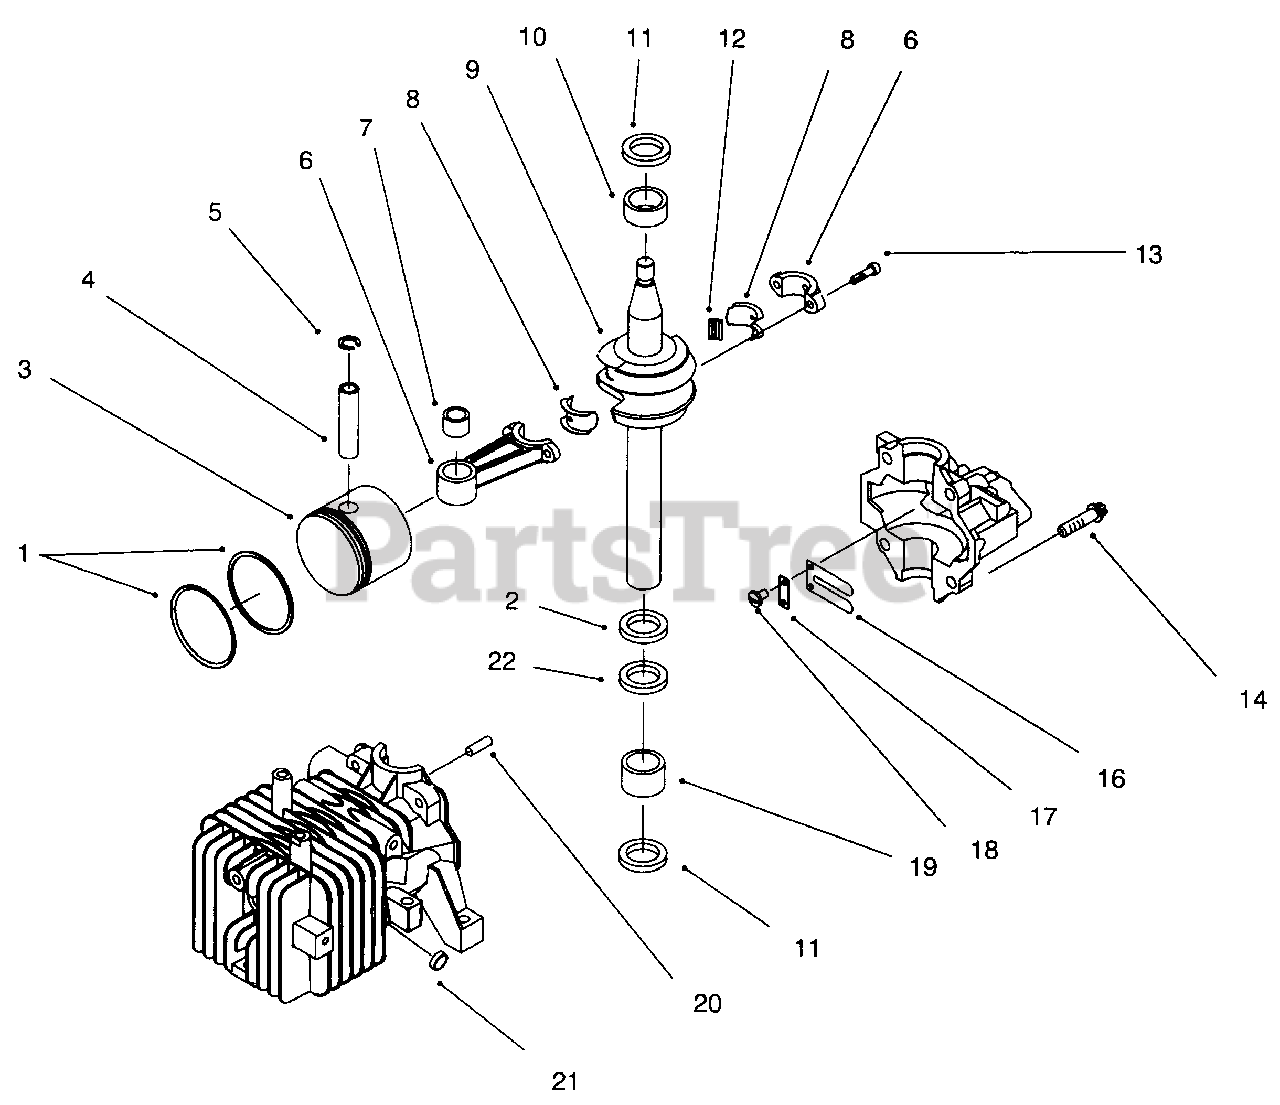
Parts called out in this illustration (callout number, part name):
1	Set-Rings, Piston
2	Bearing-Thrust
3	Piston & Connecting Rod (Incl. Ref. #1, 3-7 & 13)
4	Pin-Wrist
5	Ring-Retaining
6	Connecting Rod Assembly (Incl. Ref. #8, 12 & 13)
8	Liner-Split (Set of 2)
9	Crankshaft
10	Bearing-Upper Main
11	Seal-Oil
12	Bearing-Needle
13	Screw-Hex. Hd.
14	Screw-Hex. Washer Hd.
16	Reed-Carburetor
17	Reed-Backup Plate
19	Bearing-Needle
21	Plug-Core
22	Washer-Thrust
